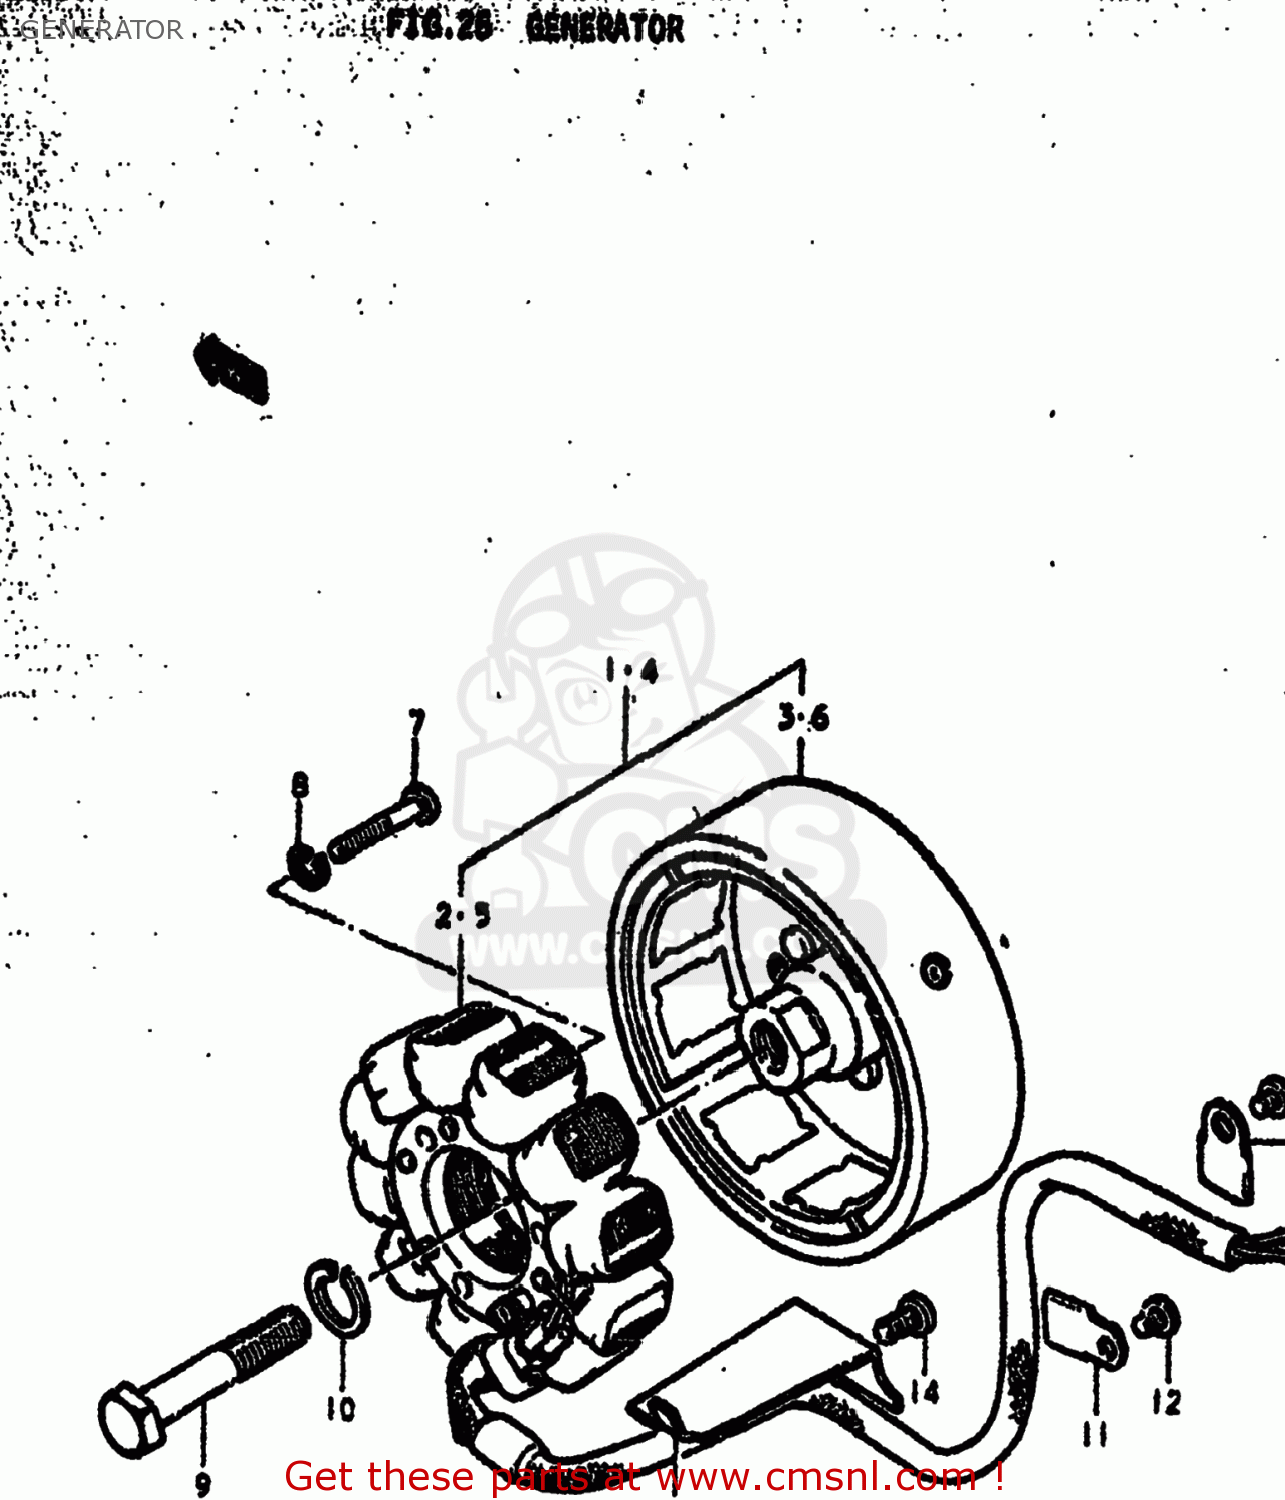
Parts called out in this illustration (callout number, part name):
1	GENERATOR ASSEMBLY
2	STARTER ASSY
3	ROTOR ASSEMBLY
4	GENERATOR ASSEMBLY
5	STATOR ASSEMBLY
6	ROTOR ASSEMBLY
7	SCREW
8	LOCK WASHER
9	BOLT 12X45
10	WASHER,LOCK 12
11	CLAMP,GENERATOR LEAD WIRE
12	SCREW
13	CLAMP,GENERATOR LEAD WIRE
14	SCREW
